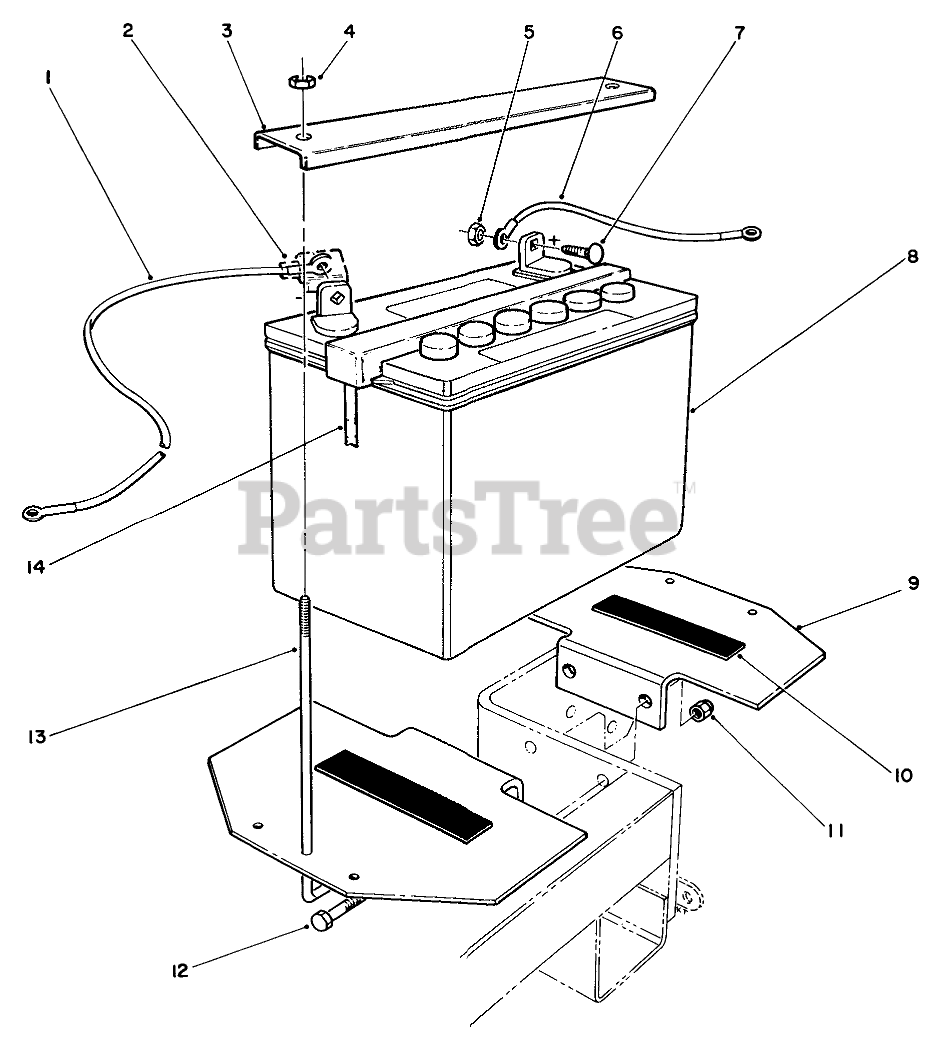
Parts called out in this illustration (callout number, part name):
1	WIRE ASM
2	BOOT-TERMINAL, BLACK
3	BATTERY STRAP R/B
4	NUT-LOCK, NI
5	NUT-KEPS
6	WIRE ASM
7	BOLT-CARR
8	Battery
9	Holder-Battery
10	PAD-TANK, FUEL
11	NUT-LOCK, NI
12	SCREW-HH
13	ROD-SUPPORT, BATTERY
14	TUBE-VENT
